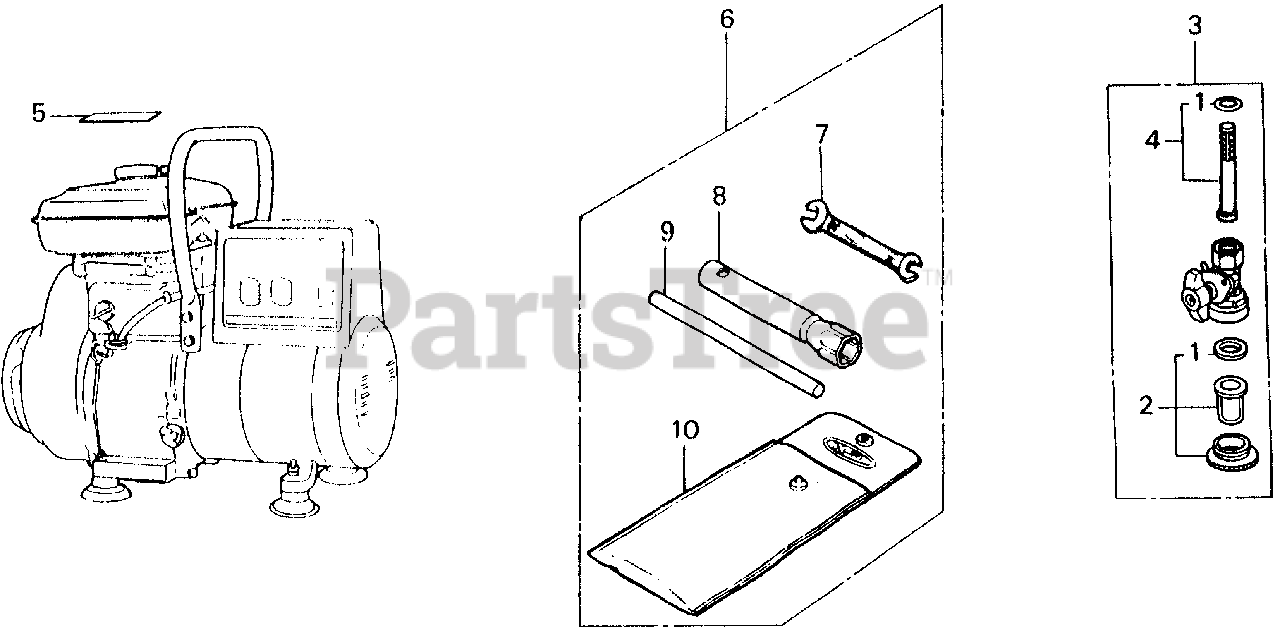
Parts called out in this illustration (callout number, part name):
1	GASKET SET, VALVE
2	CUP SET, FUEL STRAINER
3	PETCOCK ASSY.
4	SCREEN SET
5	MARK, CAUTION (CO)(ENGLISH/FRENCH)(SPANISH)
6	TOOL KIT (N/A: SEE ASSEMBLY)
7	WRENCH (10X12) (OPEN END)
8	WRENCH, BOX (P21)
9	BAR A, HANDLE
10	BAG, TOOL
